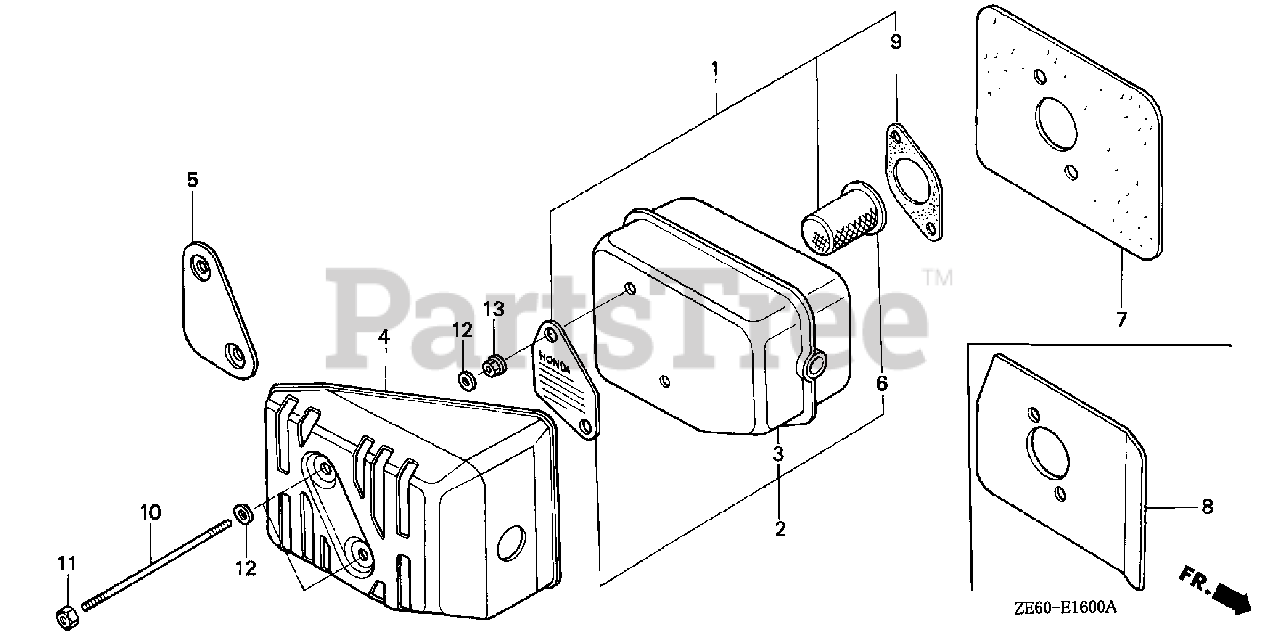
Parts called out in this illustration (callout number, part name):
1	ARRESTER KIT, SPARK
4	PROTECTOR, MUFFLER
6	ARRESTER KIT, SPARK Use up to Engine SN 2519464.
6	ARRESTER KIT, SPARK
8	GASKET, MUFFLER
9	GASKET, MUFFLER Use up to Engine SN 2519464.
9	GASKET, MUFFLER
10	BOLT, STUD (6X85)
11	NUT, SELF-LOCK (6MM)
